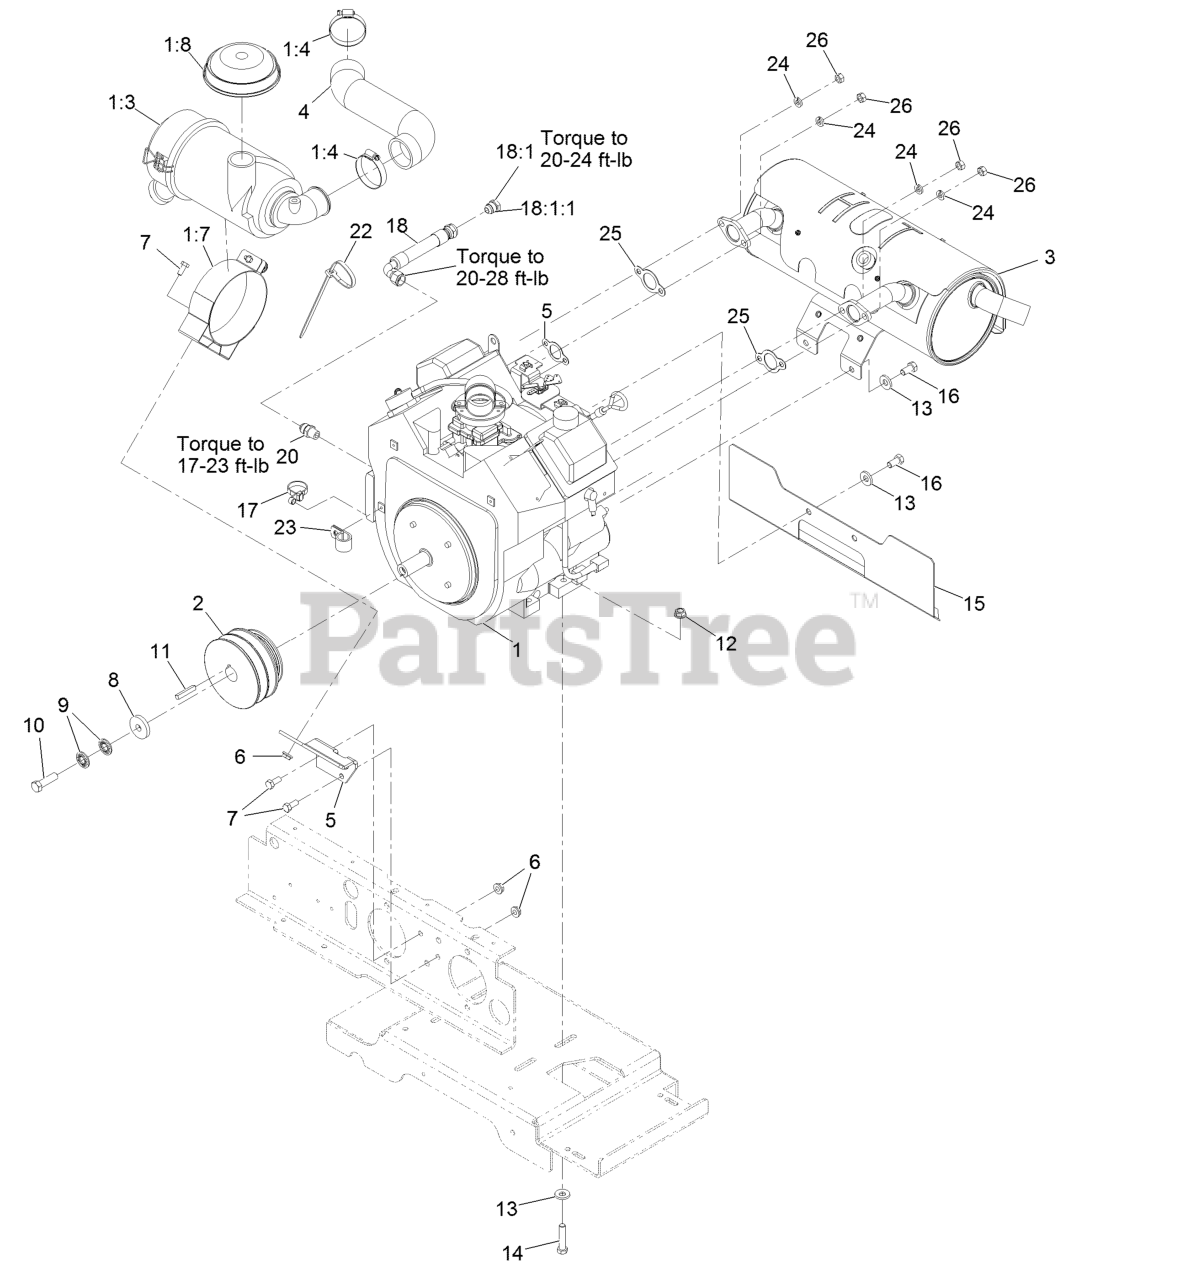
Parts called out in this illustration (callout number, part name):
1:3	AIR CLEANER CANISTER ASM
1:4	CLAMP-HOSE
1:7	BRACKET-FILTER, AIR
1:8	HOOD-CLEANER, 2" AIR INTA
4	HOSE-AIR INTAKE
5	BRACKET-FILTER, AIR
7	SCREW-HH
8	WASHER-CLUTCH
9	WASHER-SPRING
10	SCREW-HH
11	KEY-SQUARE
12	NUT-HHF, WHIZ
13	WASHER-BELLEVILLE
14	SCREW-HH
15	SHIELD-EXHAUST
16	SCREW-HH
17	Tie-Cable
18	OIL DRAIN HOSE ASM
18:1	PLUG-HH
18:1:1	O-RING
20	FITTING-STRAIGHT
22	TIE-PLASTIC
23	CLIP-LOOM
24	WASHER-LOCK
26	NUT-HEX
